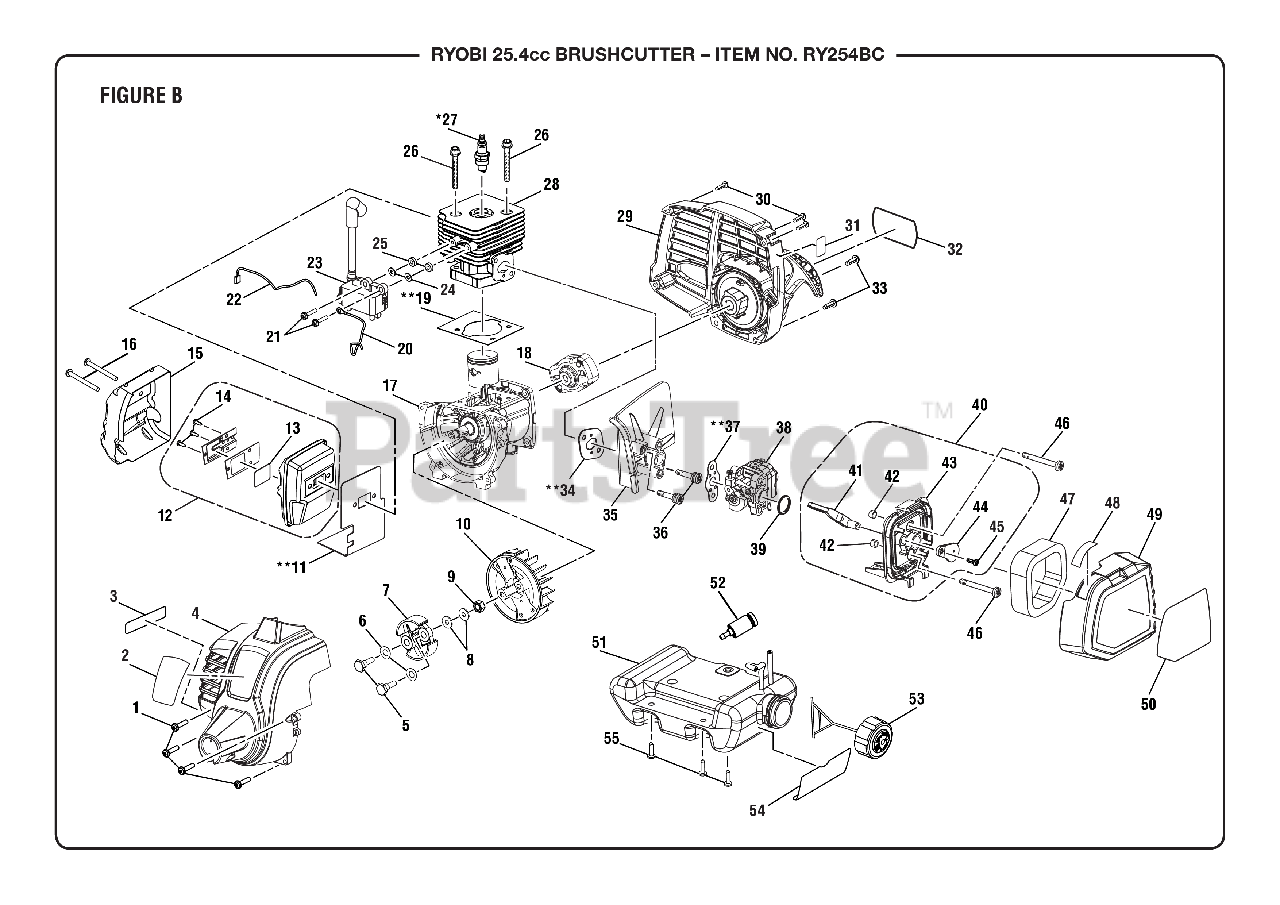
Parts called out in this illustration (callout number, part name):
1	Cap Screw w/Washer (M5 x 16 mm, T25 Torx Soc. Hd.)
2	Logo Label (Front)
3	Warning Label (Combustion)
4	Front Housing Assembly w/ Labels
5	Clutch Shoulder Bolt (M6 x 22.5 mm, Hex Hd.)
6	Washer (Curved)
7	Clutch Assembly
8	Washer (ID6 x OD15 x 1.2t)
9	Flange Nut (M8, Flywheel)
11	Muffler Gasket
12	Muffler Assembly
13	SCREEN
14	Screw (6-20 x 1/4 in., T20 Torx Pan Hd. S.T.)
15	HEAT SHIELD
16	Screw (M5 x 50 mm, Torx Slotted Recessed Pan Hd.)
17	Crankcase Assembly
18	Starter Cup
19	Gasket
20	Lead Wire Assembly, Red
21	Screw w/Washer (M4 x 19 mm, T20 Torx Pan Hd. S.T.)
22	Lead Wire Assembly, Black
23	Coil Boot Assembly
24	Flat Washer (OD10 x ID42 x 1t)
25	Phenolic Spacer (Ignition Module)
26	Screw (M5 x 22 mm, T25 Torx Soc. Hd.)
27	Spark Plug (Champion RCJ6Y)
29	Screw (M4 x 18 mm, T20 Torx Pan Hd. S.T.)
30	Screw (M4 x 1.41 mm x 18 mm, T20 Torx Pan Hd. T.F)
31	Primer Bulb Location Label
32	Shoulder Screw (M4 x 14 mm, T25 Torx Truss Hd.
33	Cap Screw w/Washers (M5 x 16 mm, T25 Torx Soc. Hd.)
34	Gasket (Heat Dam)
35	Screw (M5 x 30 mm, T25 Torx Pan Hd. S.T.)
36	Screw (M5 x 27 mm, T25 Torx Pan Hd. S.T.)
37	Gasket
38	Carburetor Assembly
39	Carburetor O-Ring
40	Airbox Base Assembly
41	Compression Limiters
42	Washer (ID5.8 x OD11.5 x 1.7t)
43	Air Box Base
44	Screw (M4 x 12 mm, T20 Torx Pan Hd. S.T.)
45	Screw (M4 x 12 mm, Slotted Recessed Pan Hd.)
46	Screw (M5 x 44 mm,T25 Torx Hd. Carburetor)
47	Air Filter (Element)
48	Choke Position Label
49	Airbox Cover (Inc. Key Nos. 48 & 50)
50	Starting Instructions Label
51	Fuel Tank and Cap Assembly
52	Fuel Filter
53	Fuel Cap Assembly
54	Fuel Mixture Label
55	Shoulder Screw w/Washer (M4 x 14 mm, T25 Torx Truss Hd.)
